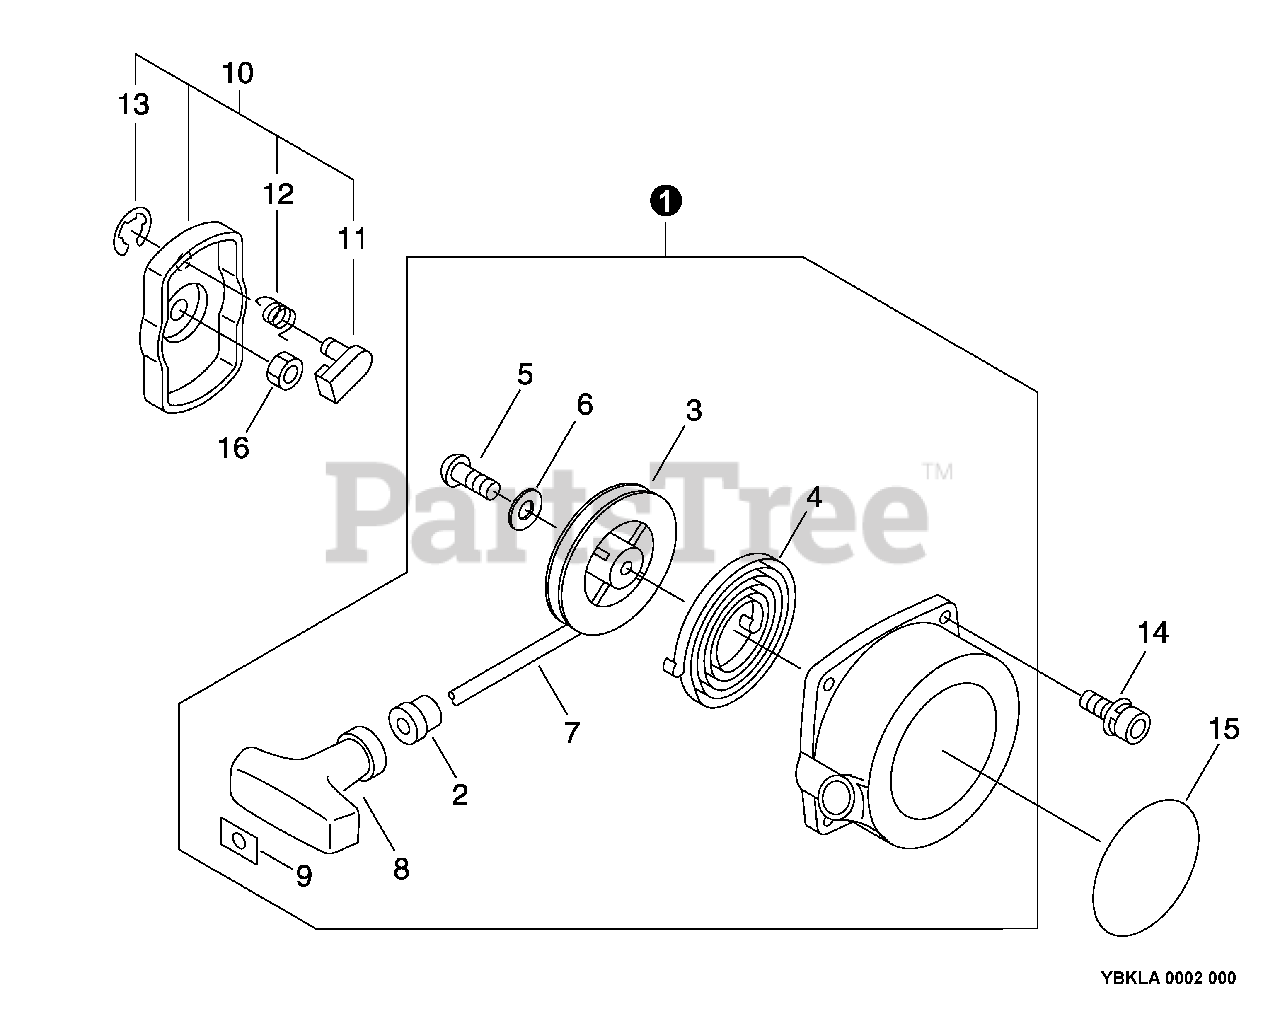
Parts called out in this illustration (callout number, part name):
1	STARTER ASSY
2	GUIDE, ROPE
3	REEL, ROPE
4	SPRING, REWIND
7	ROPE, STARTER - 4X950
8	GRIP, STARTER
9	RETAINER, ROPE
10	STARTER PAWL ASSY
11	PAWL, STARTER
12	SPRING, RETURN
13	RING, RETAINING
14	SCREW - 4X20
15	LABEL - ECHO
